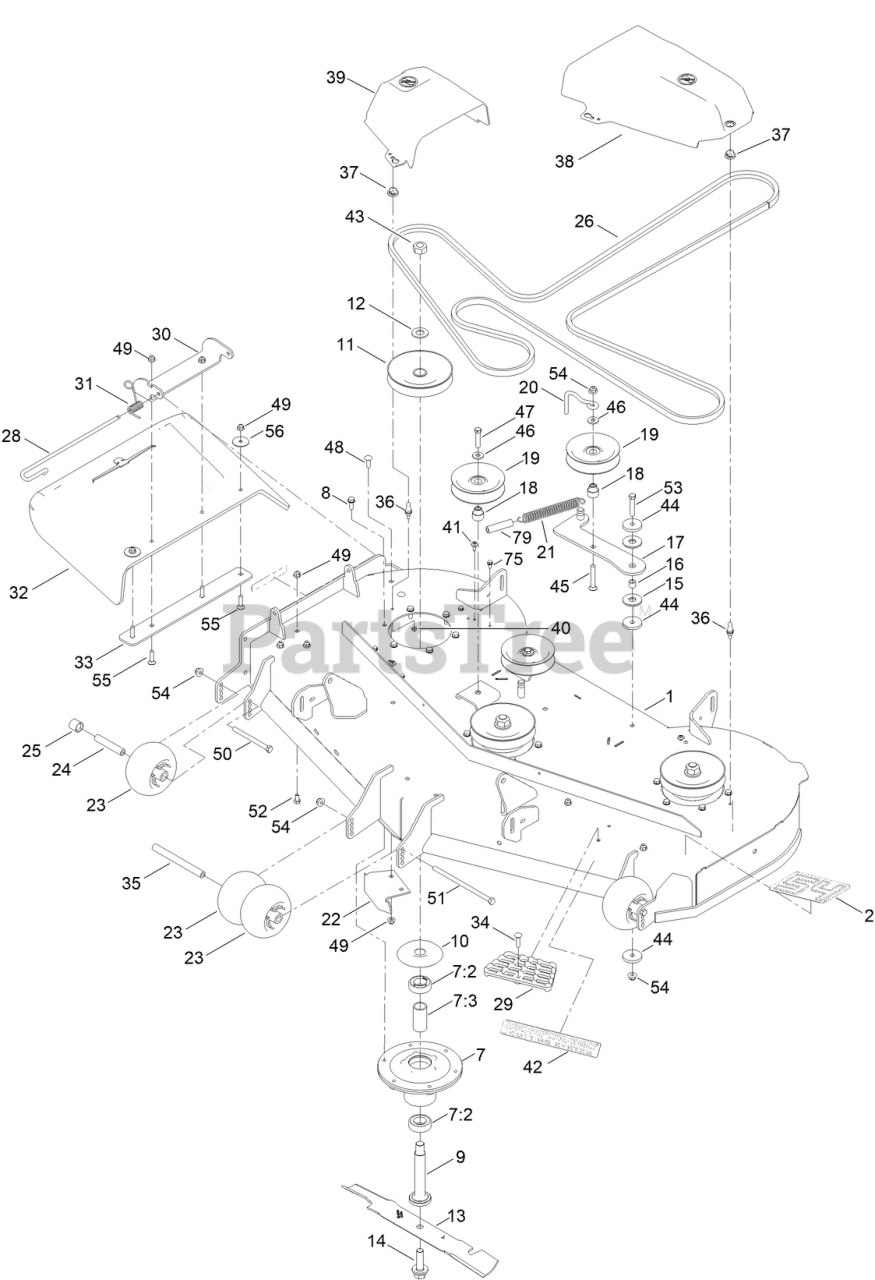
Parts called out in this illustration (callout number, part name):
1	54 IN DECK DECAL ASM
2	DECAL - DECK 54
7	SPINDLE ASM
7:2	BEARING-BALL
7:3	SPACER-BEARING
8	SCREW-TAPTITE
9	SHAFT-SPINDLE
10	SHIELD-BEARING
11	PULLEY
12	WASHER
13	BLADE-HI FLO
14	SCREW-BLADE
15	WASHER-FRICTION, COMPOSITE
16	SPACER
17	IDLER ARM ASM
18	BUSHING-IDLER
19	PULLEY-IDLER, FLAT
20	GUIDE-BELT, IDLER
21	SPRING-EXTENSION
22	BAFFLE-CUTOFF
23	ROLLER-SCALP, ANTI
24	TUBE-SPANNER
25	SPACER-AXLE, REAR
26	V-BELT (B SEC 174.25 EL)
28	PIN-CHUTE
29	STEP-DECK
30	BRACKET-DEFLECTOR, UPPER
31	SPRING-TORSION
32	DEFLECTOR - MOLDED
33	PLATE-DEFLECTOR
34	BOLT-CARRIAGE
35	SPACER-WHEEL
36	STUD-BALL
37	GROMMET-BALL
38	COVER-BELT, LH
39	COVER-BELT, RH
40	NUT-LOCK
41	SCREW-SHOULDER
42	DECAL - IRON FORGED
43	NUT-HEX
44	WASHER-PLAIN
45	SCREW-CARR
46	WASHER-HARDENED
47	SCREW-HH
48	SCREW-CARR
49	NUT-HF, NI
50	SCREW-HH
51	SCREW-HH
52	SCREW-HH
53	SCREW-HH
54	NUT-HF, NI
55	SCREW-CARR
56	WASHER-FLAT
75	SCREW-HWH
79	HOSE-BREATHER
